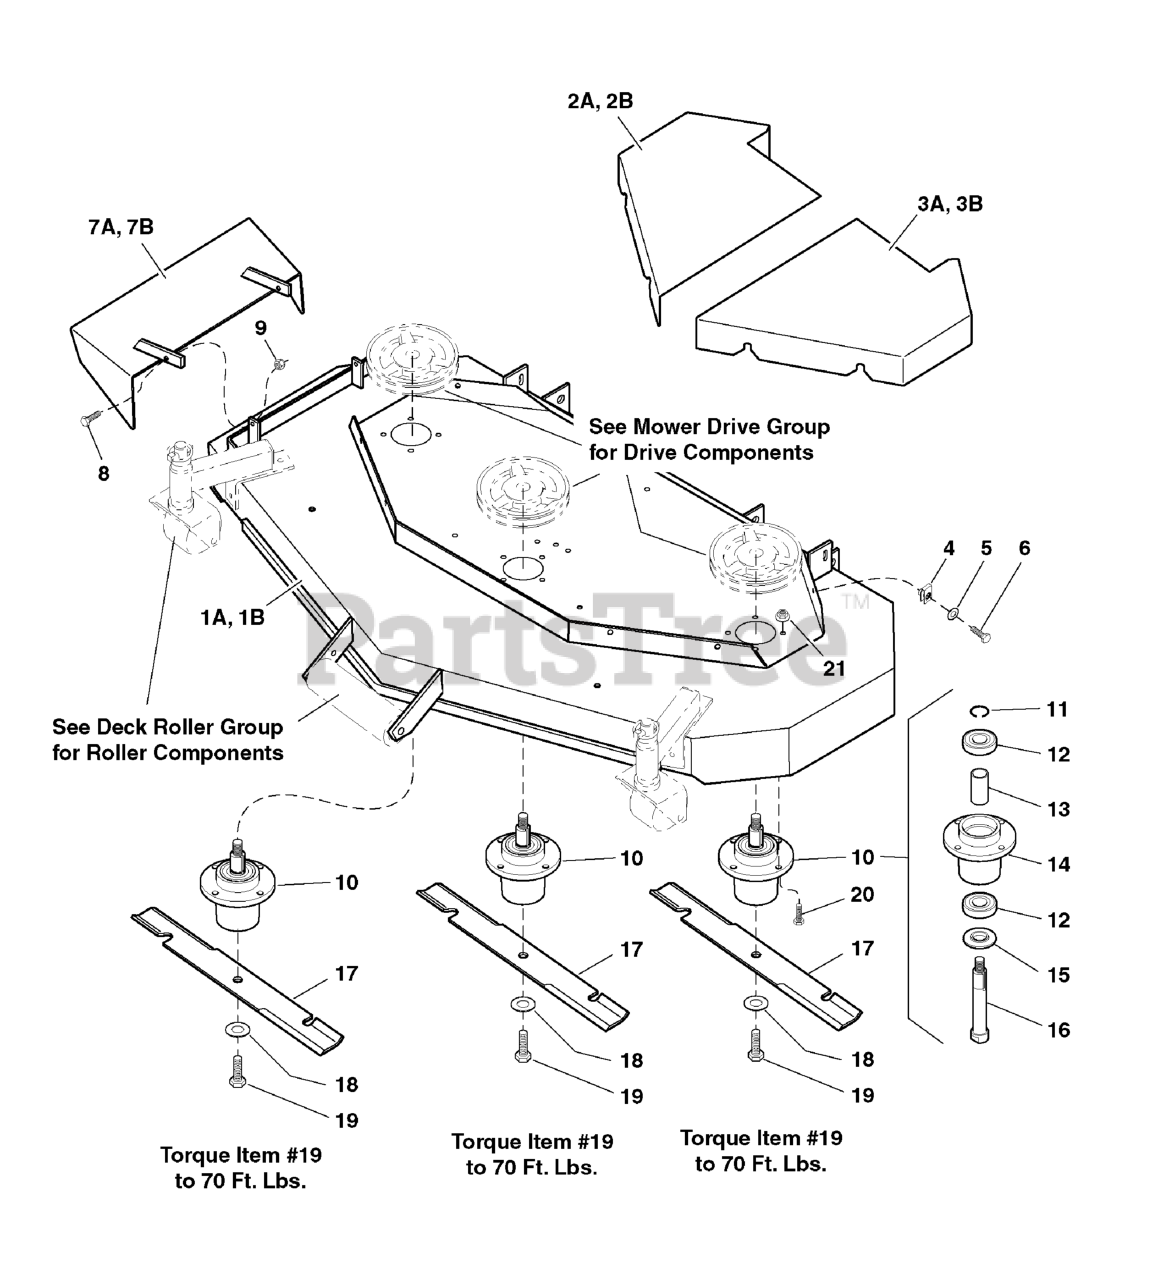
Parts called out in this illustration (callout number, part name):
1A	DECK SHELL W/DECALS, 61"
1B	DECK SHELL W/ DECALS, 61"
2A	SPINDLE COVER-RH
2B	SPINDLE COVER-RH
3A	SPINDLE COVER-LH
3B	SPINDLE COVER-LH
4	BODY CLIP, 5/16-18-7GA MATERIAL
5	WASHER, 5/16" SAE
6	BOLT, 5/16-18 X 3/4 GD5
7A	DISCHARGE CHUTE
7B	DISCHARGE CHUTE
8	BOLT, 5/16-18 X 1 GD5 YZ
9	NUT, 5/16-18 Hex Nylon Lock
10	* SPINDLE ASSEMBLY, Complete
17	MOWER BLADE, 21"
18	WASHER, 5/8" GRADE 8, YZ
19	BOLT, 5/8-11 X 1-3/4 GD8
20	BOLT, 5/16-18 x 1-1/8
21	NUT, 5/16-18 HEX SERRATED FLANGE (LARGE)
